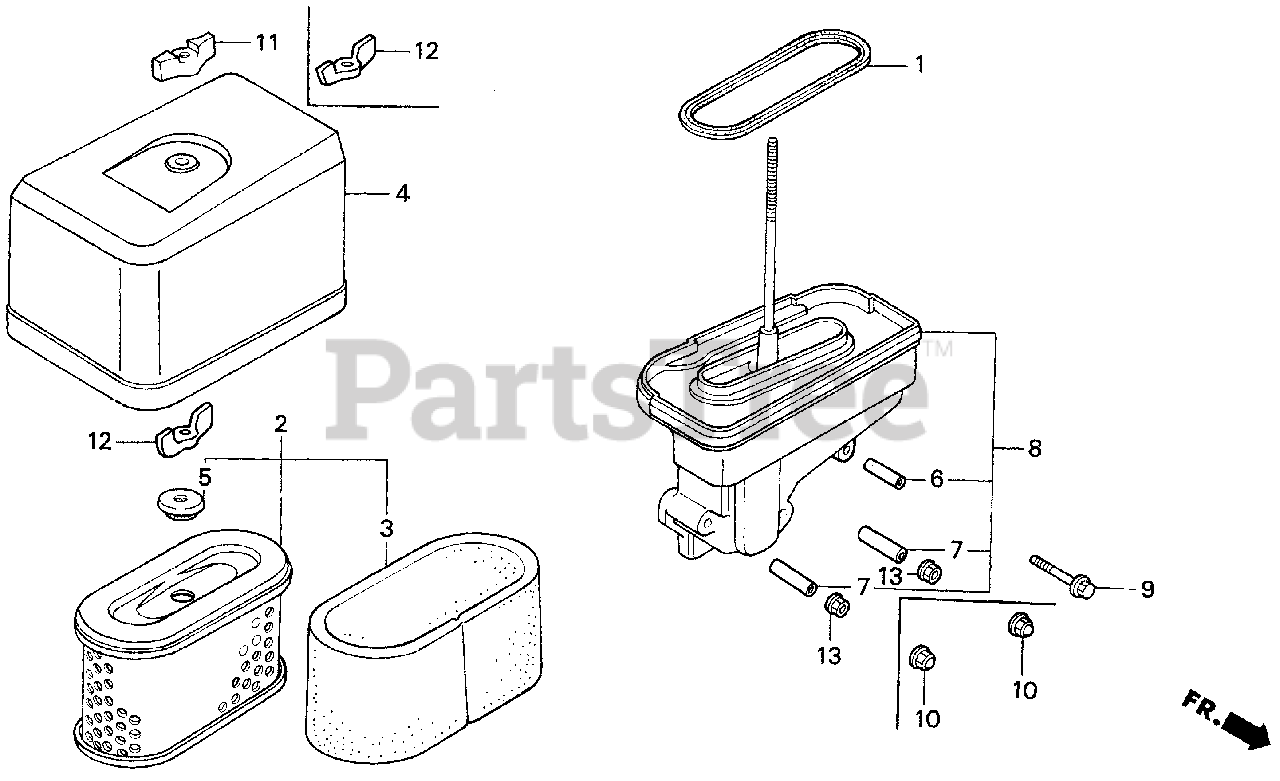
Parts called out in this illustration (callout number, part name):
1	GASKET, ELBOW
2	ELEMENT, AIR CLEANER (Honda Code 3133808). (METAL BASE)
2	ELEMENT, AIR CLEANER (Honda Code 5248299). (METAL BASE)
3	FILTER (OUTER)
4	COVER, AIR CLEANER (DUAL)
5	GROMMET, AIR CLEANER
6	COLLAR, AIR CLEANER
7	COLLAR, AIR CLEANER
8	ELBOW, AIR CLEANER
9	BOLT, FLANGE (6X35)
10	NUT, CAP (6MM)
11	WINGNUT (6MM)
12	WINGNUT, TOOL BOX SETTING
